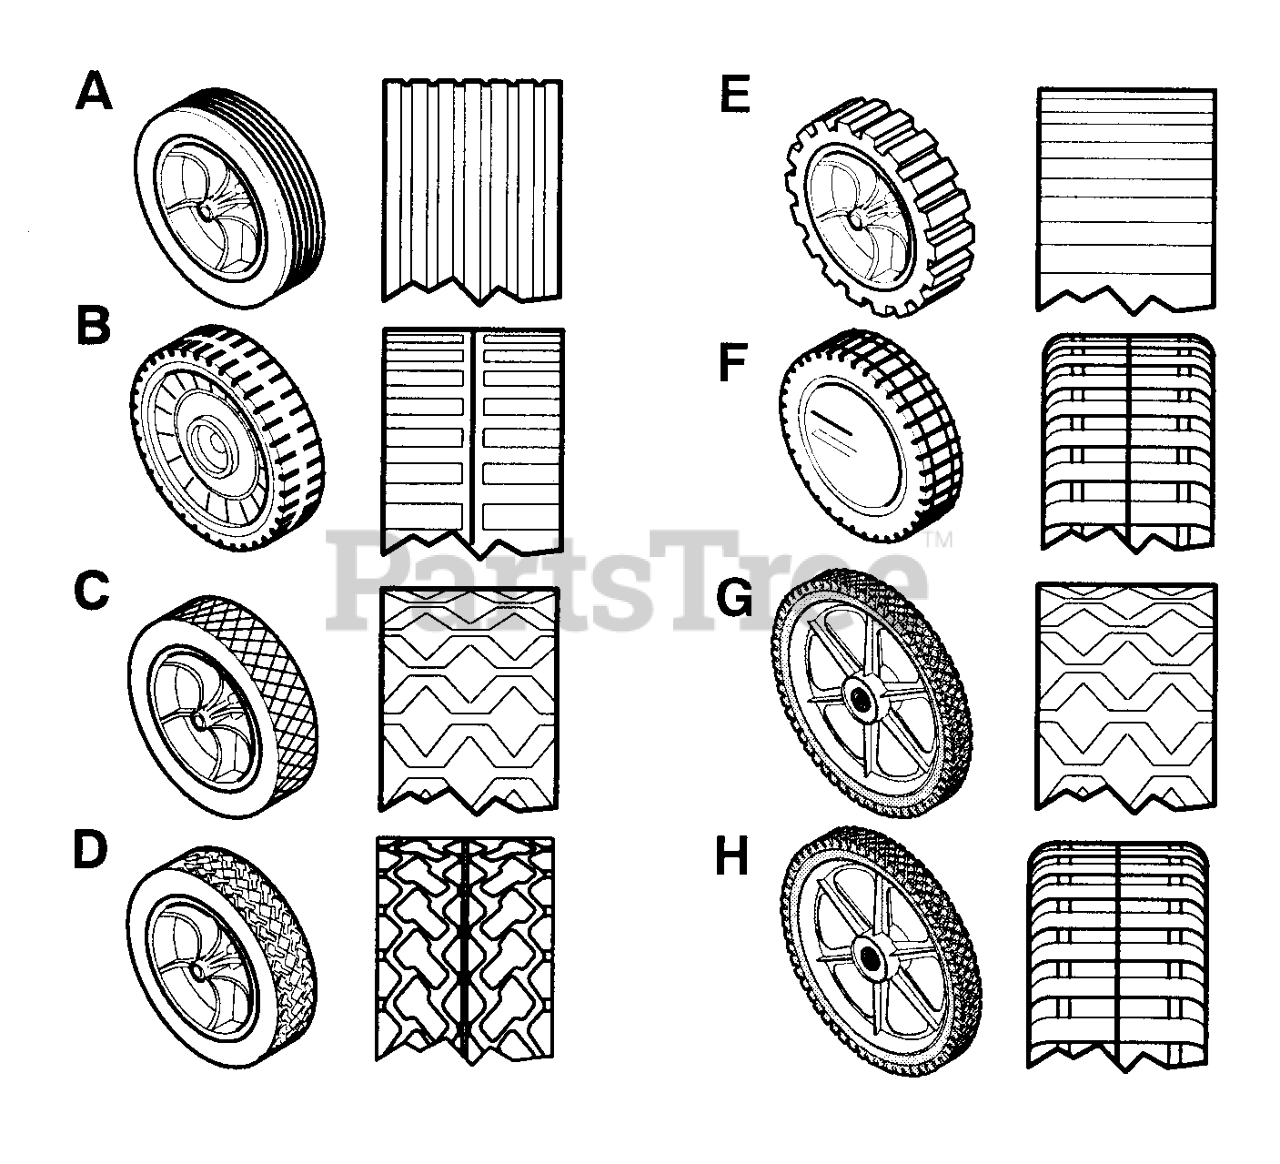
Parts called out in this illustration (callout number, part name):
A	WHEEL & TIRE ASSEMBLY, Light Gray, 8"
A	8-inch Plastic, Dark Gray
A	8-inch Metal, White
B	7-inch Plastic, White
B	7-inch Plastic, Light Gray
B	7-inch Plastic, Dark Gray
C	6-inch Plastic, White
C	7-inch Plastic, White
C	7-inch Plastic, Light Gray
C	7-inch Plastic, Dark Gray
C	8-inch Plastic, White
C	8-inch Plastic, Light Gray
C	8-inch Plastic, Dark Gray
C	8-inch Metal, White
D	7-inch Plastic, White
D	WHEEL & TIRE ASSEMBLY, White, 8"
D	8-inch Plastic, Light Gray
D	8-inch Plastic, Dark Gray
E	WHEEL & TIRE ASSEMBLY, White, 8"
E	8-inch Plastic, Dark Gray
E	8-inch Metal, White
F	WHEEL & TIRE ASSEMBLY, White, 8"
F	8-inch Plastic, Light Gray
F	8-inch Plastic, Dark Gray
F	8-inch Ball Bearing, Light Gray
F	8-inch Ball Bearing, Dark Gray
G	14-inch, White
G	14-inch, Light Gray
G	14-inch, Dark Gray
G	WHEEL & TIRE ASSEMBLY, White, 14"
G	14-in, Ball Bearing, Light Gray
G	14-in, Ball Bearing, Dark Gray
H	14-inch, White
H	14-inch, Light Gray
H	14-inch, Dark Gray
H	WHEEL & TIRE ASSEMBLY, Ball Bearing, 14"
H	14-in, Ball Bearing, Light Gray
H	14-in, Ball Bearing, Dark Gray
